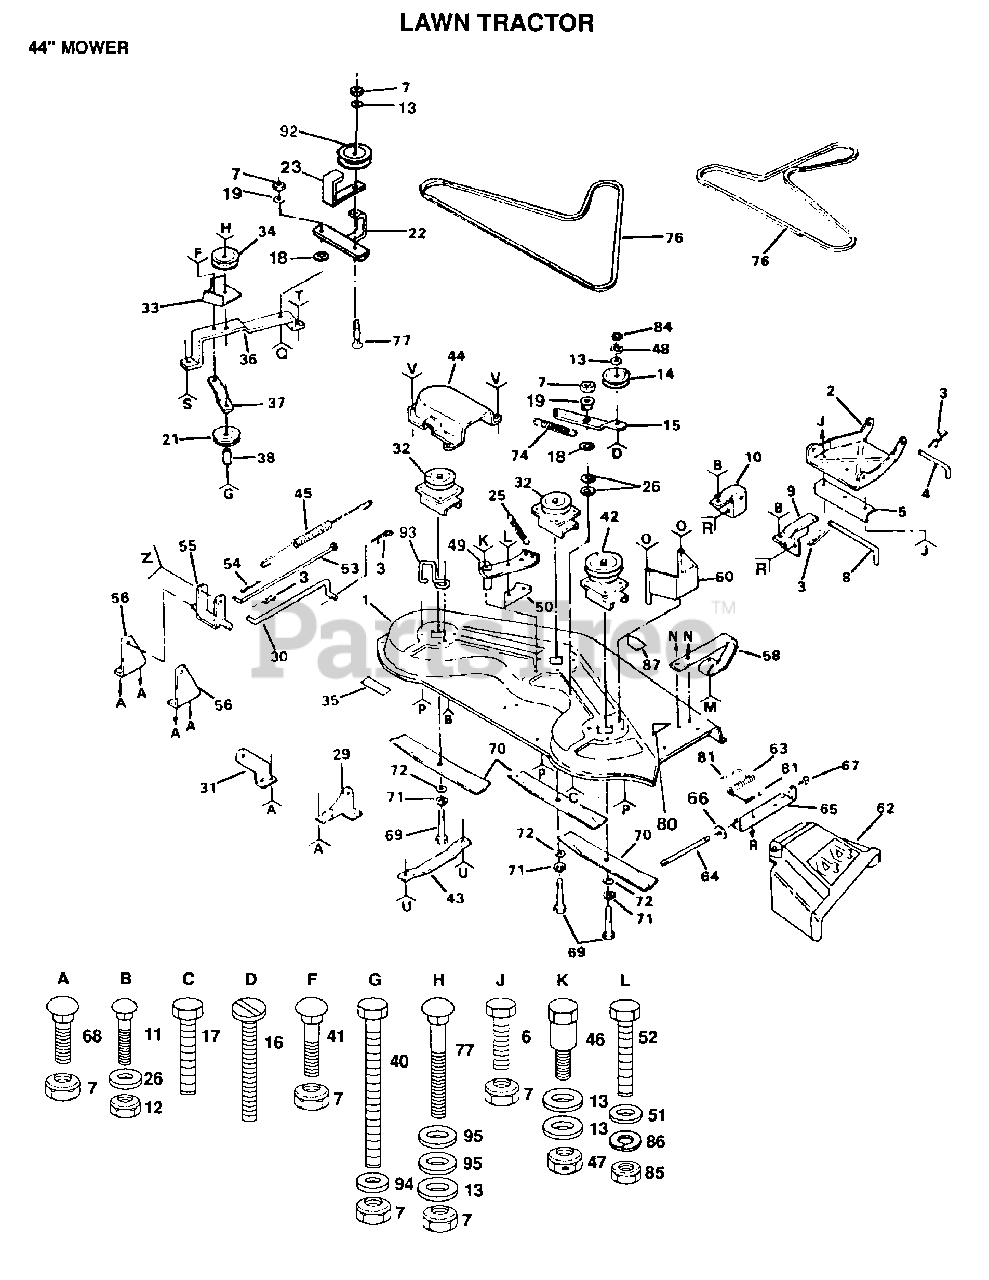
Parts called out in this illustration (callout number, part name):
2	LINK.PARALLEL
3	SPRING.RETAINER
4	"ROD, FRT. PARAL T"
5	LINK STOP
8	HINGE PIN T
9	BRACKET RH YT
10	BRACKET LH YT
11	BOLT
13	WASHER
14	IDLER.FLAT.GTV
15	ARM-IDLER YT
16	SCREW YT
18	"WASHER, WEAR LT"
19	SPACER RETAINER
21	IDLER-FLAT T
23	GUIDE BELT
25	SPRING-EXT YT
26	WASHER M
29	BRKT SUSP REAR RH
31	BRKT SUSP REAR LH
33	GUIDE-BELT YT
34	IDLER-INSIDE T
36	"SUPPORT YT, BAR"
37	BRACE-IDLER YT
38	SPACER
40	BOLT - HEX 3/8 - 16 X 3
43	RUNNER-LH M
44	GUARD YT
46	BOLT SHOULDER
47	LOCKNUT
48	LOCKWASHER
49	BRAKE ARM LT
50	BRAKE-BLOCK YTV
51	WASHER
53	ROD BRAKE YT
56	SUPPORT SHAFT YT
60	ASSY RH BELT GRD
61	BOLT
62	DEFLECTOR SHIELD
64	ROD-HINGE T
66	WASHER
67	NUT PUSH M
68	BOLT
69	BOLT.3/8-24X1-1/2
72	WASHER
76	BELT-V.79.1.MWR
77	BOLT
81	CAP-SLEEVE LT
84	NUT.HEX.3/8-16UNC
85	NUT.HEX.5/16-18
86	LOCKWASHER
87	DECAL WARING
92	PULLEY IDLER
93	BELT RETIANER
94	WASHER
95	WASHER
